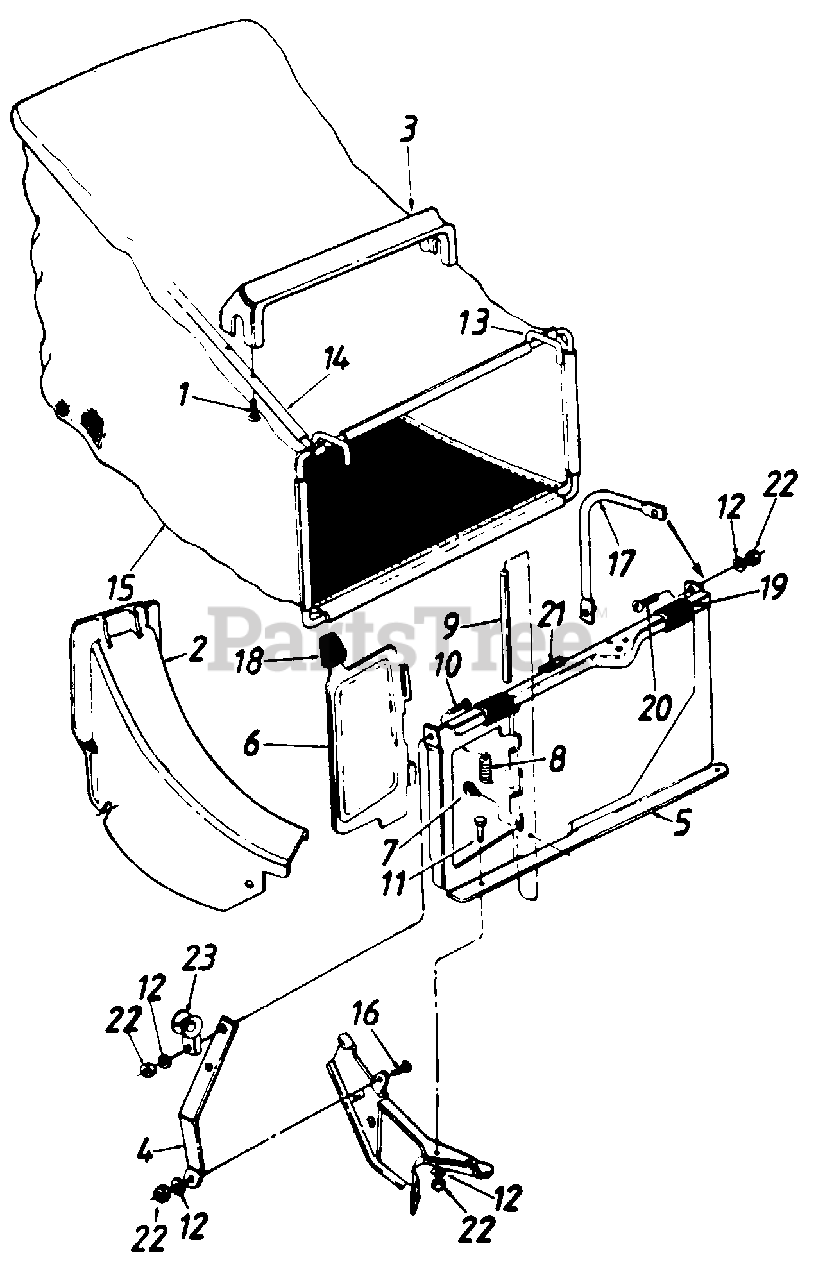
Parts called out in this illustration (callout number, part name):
1	Hex AB-Tap Scr. #12 x 1.25" Lg.
2	Rear Discharge Chute Ass'y.
3	Bag Handle
7	Hex B-Tap Scr. #10 x .38"
8	Torsion Spring
9	Pivot Pin
10	Truss Mach. Scr. 1/4- 20 x 3/4" Lg.
11	Hex Bolt 1/4- 20 x 50" Lg.
12	L-Wash. 1/4" I.D.
15	21" Rear Discharge Grass Bag
16	Hex Bolt 1/4-20 x .62 Lg.
17	Catcher Panel Support Arm
18	Door Grip
19	Panel Clip
20	Truss Mach. Scr. 1/4-20 x .62" Lg.
21	Foam Strip
22	Hex Nut 1/4-20 Thd.
23	Rope Guide
